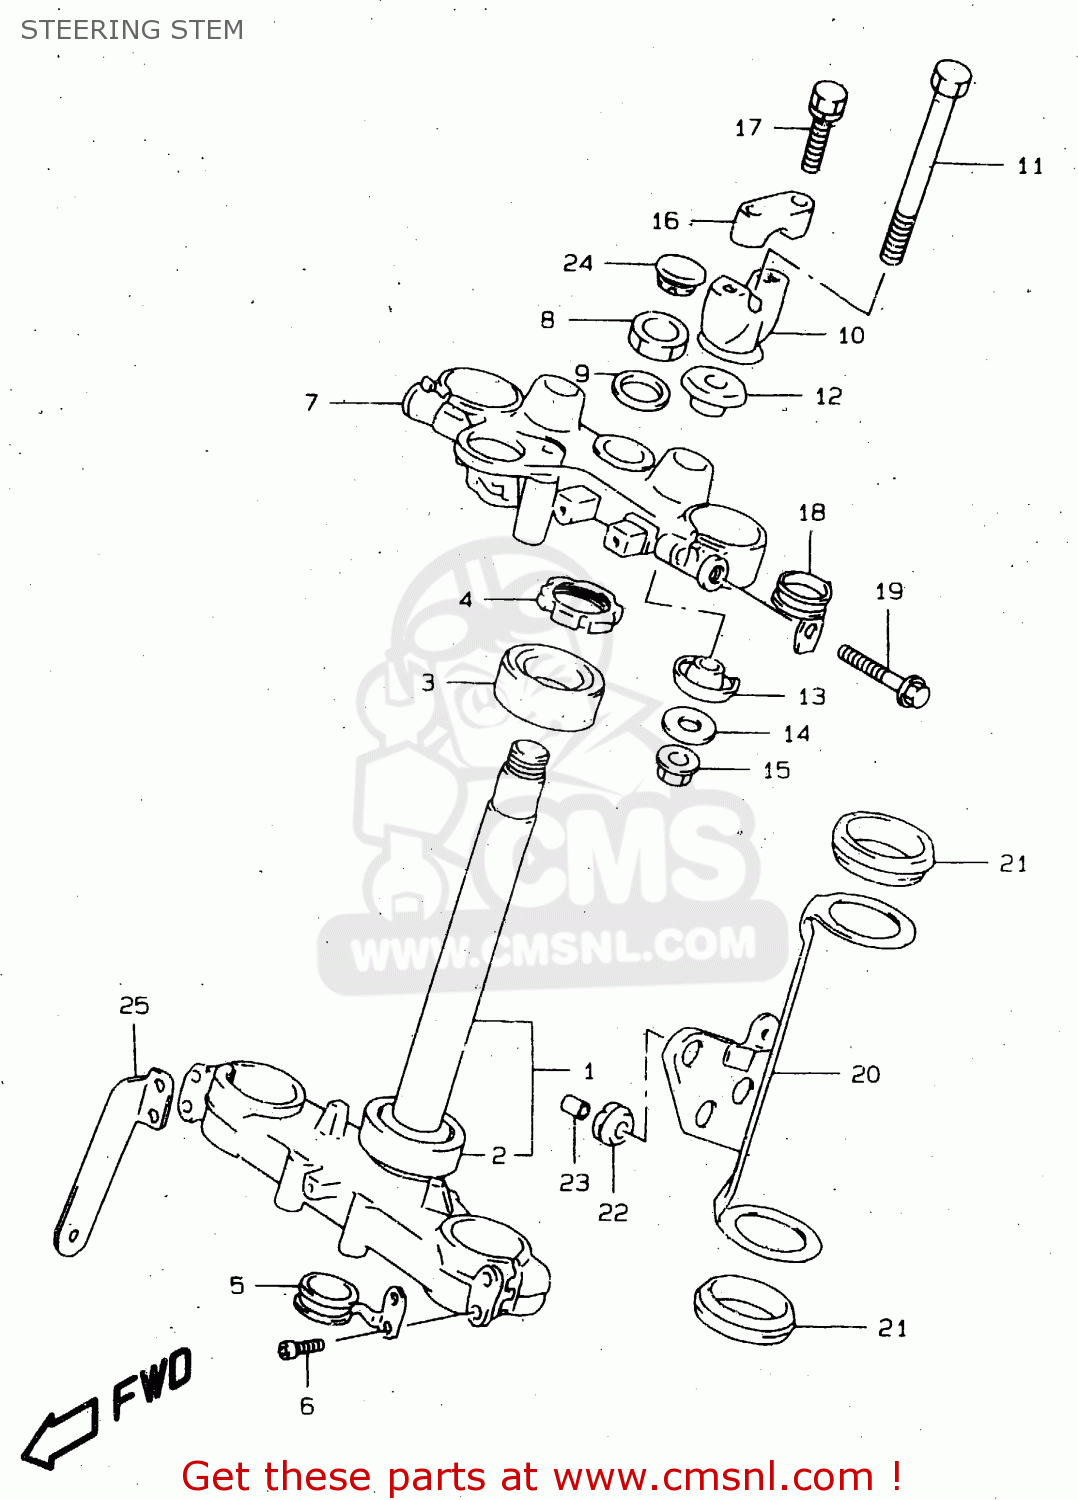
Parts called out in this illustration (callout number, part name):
1	STEM,STEERING
2	BEARING(30X52X16)
3	BEARING(30X52X16)
4	NUT,STEERING
5	CLAMP
6	BOLT
7	HEAD,STEERING STEM
8	NUT
9	WASHER,STEM HEAD(24.5X34X1.6)
10	HOLDER,HANDLE LWR
11	BOLT
12	DAMPER,UPR
13	DAMPER,LWR
14	WASHER,HANDLEBAR HOLDER
15	NUT
16	HOLDER,HANDLE UPR
17	BOLT
18	CLIP
19	BOLT
20	COVER,FORK,R
21	DAMPER,HEADLAMP HSG BRACKET
22	CUSHION
23	SPACER(6.5X10X10)
24	CAP(OD:20)
25	BRACKET,FR SIDE REFLECTOR,R
